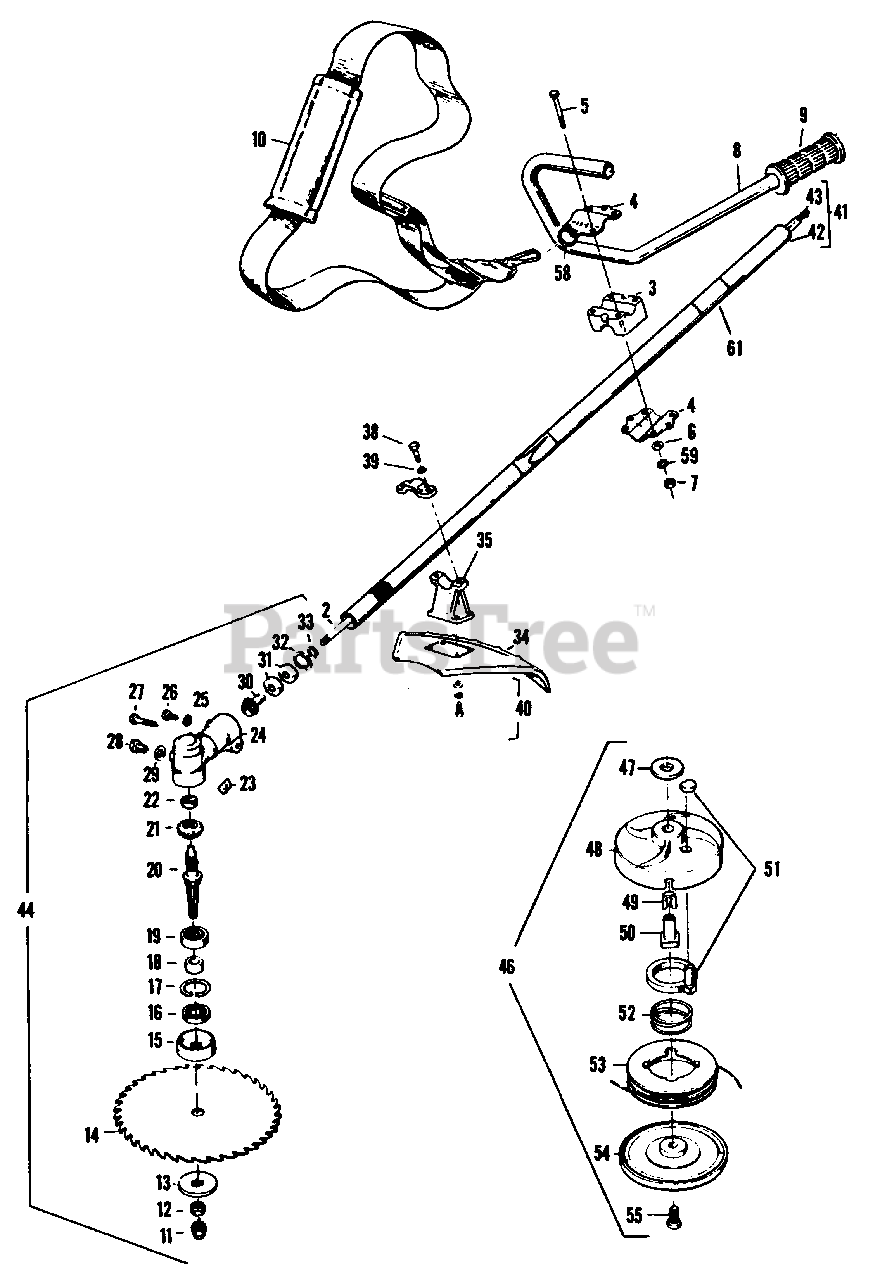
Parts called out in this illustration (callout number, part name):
1	"O" Ring-Shoulder Harness
2	Lockwasher-Handlebar
3	Handle Bar Block
4	Handle Bar Clamp
5	Bolt-Handle Bar
6	Washer-Handle Bar
8	Barrier Handle Bar
9	Grip-Handle Bar
10	Shoulder Strap
11	Locknut
13	Blade Adapter-Lower
14	10" Brush Blade
15	Blade Adapter-Upper
16	Oil Seal
17	Snap Ring
18	Collar-Shaft
19	Ball Bearing
20	Shaft-Arbor
21	Gear-Bevel
22	Bearing-Gear Box
23	Fiber-Filler Washer
24	Housing-Gear Box
25	Lock Washer-Housing Bolt
27	Housing Bolt
28	Oil Plug
30	Pinion Gear
31	Bearing-Pinion Gear
32	Snap Ring-Gear Housing Bearing
33	Snap Ring-Gear Housing
34	Splash Deflector
35	Shield Mounting Bracket Assy
40	Shield Mounting Kit
41	48" Drive Shaft Housing and Drive Shaft Assy. (Inc. 1 & 2)
42	48" Drive Shaft Hsg. w/Bearings
43	Drive Shaft
44	Transmission Assy. (Inc. 11-33)
46	Cutting Head Assy
49	Line Saver
50	Drive Adaptor
51	Lock Ring and Button-Release Assembly
54	Cover-Cutting Head
55	Screw-Cover
